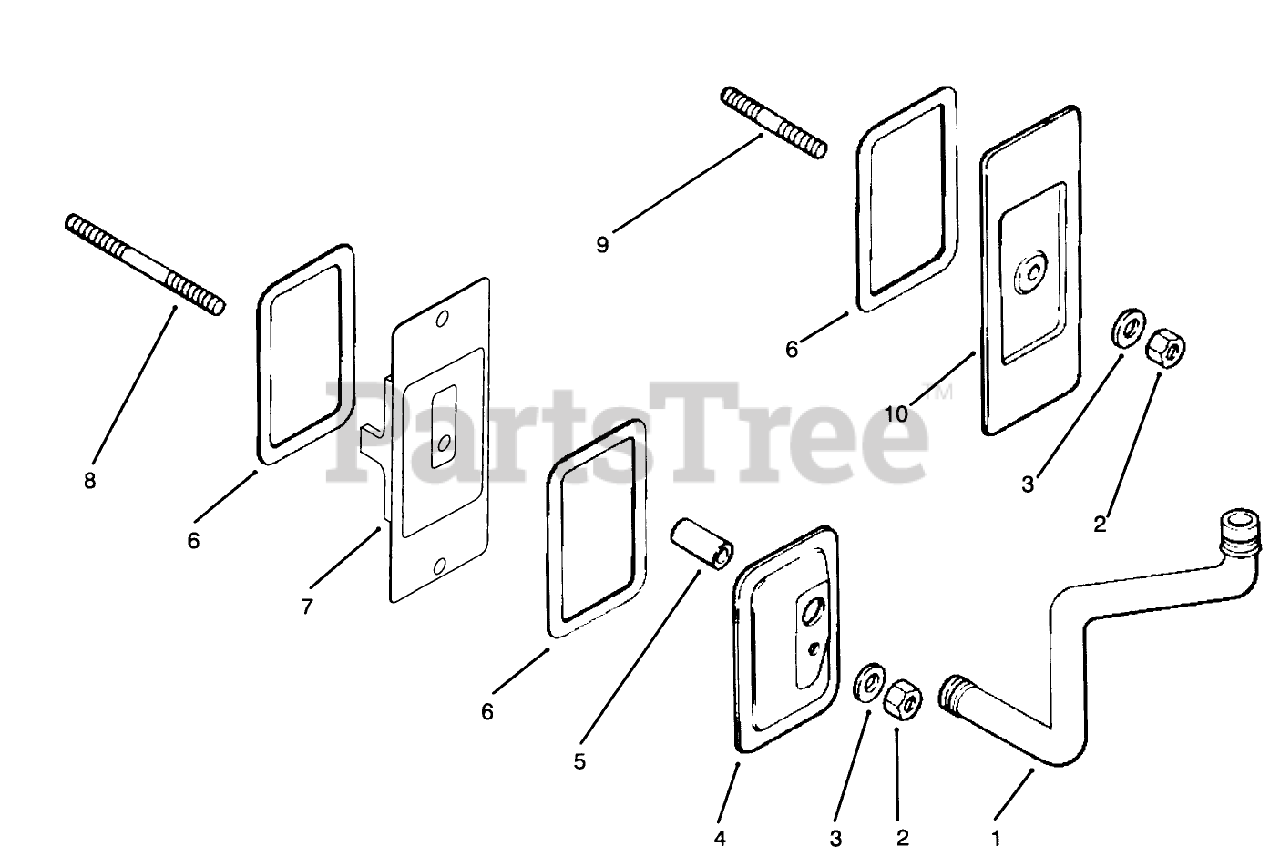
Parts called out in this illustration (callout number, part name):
1	Hose-Breather
2	Nut
3	Washer
4	Cover-Upper Cylinder Valve
5	Seal-Breather
6	Gasket-Cover
7	Breather Asm
8	Stud
9	Stud-Valve Cover
10	Cover-Cylinder Valve
